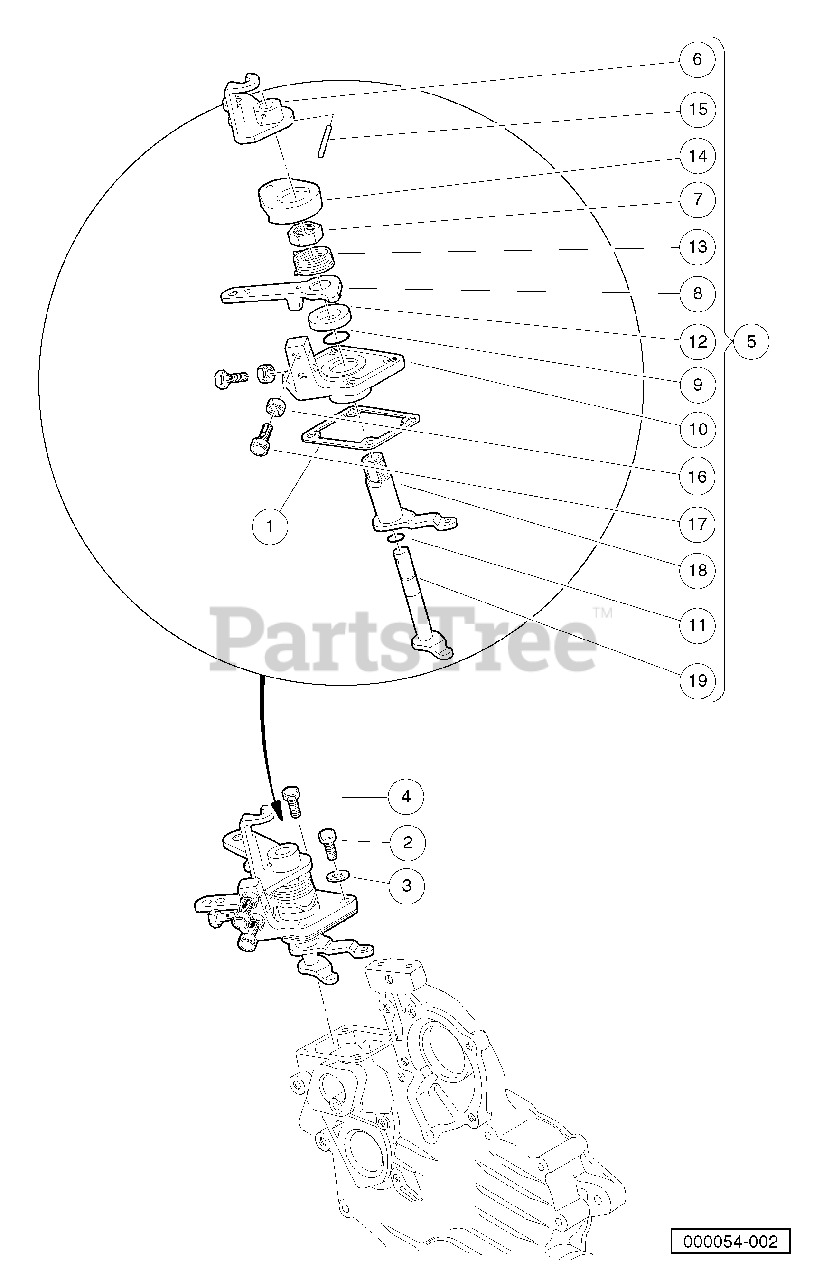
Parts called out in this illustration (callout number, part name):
1	Gasket, Control Plate
2	Bolt, M6 X 1 X 30
3	Gasket, 6 X 10
4	Bolt, D722 Intake Manfld Lower
5	Assembly, Speed Plate
6	Lever, Engine Stop
7	Nut, Speed Control
8	Lever, Speed Control
9	O Ring, 19 X 16
10	Plate, Speed Control
11	O Ring, 9 X 7
12	Collar, Lever
13	Spring, Return
14	Cap, Speed Cntrl Plate Rtrn
15	Pin, Spring, Speed Plate
16	Nut, Speed Control
17	Bolt, Speed Control
18	Lever, Governor
19	Shaft, Governor Lever
